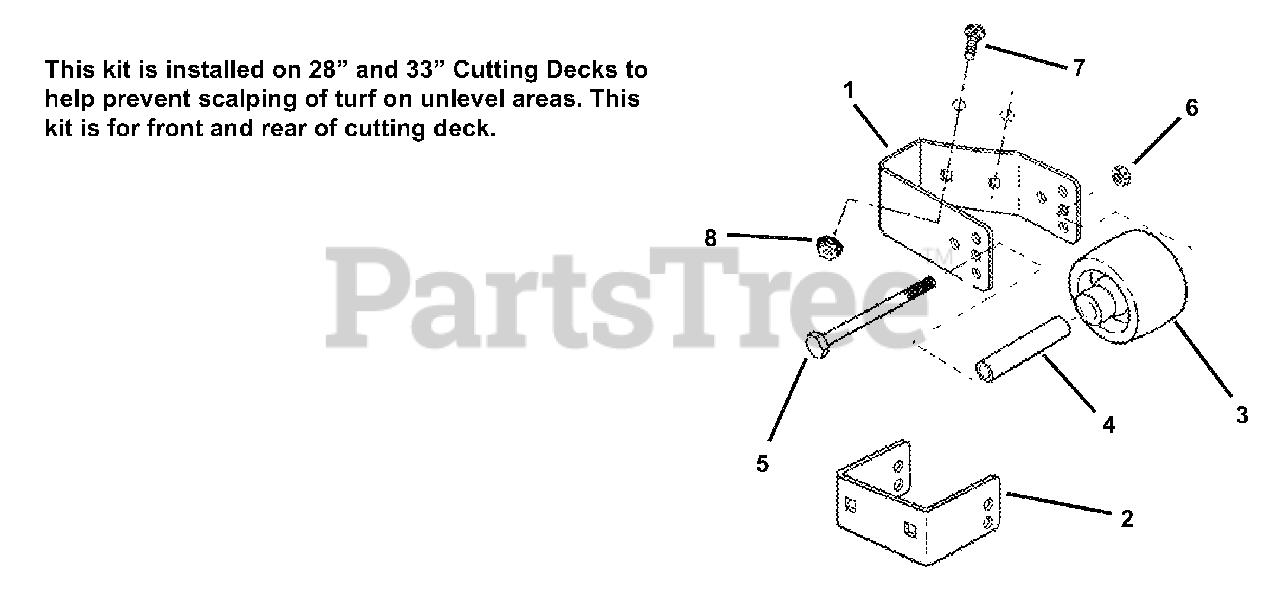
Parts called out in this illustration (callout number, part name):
1	BRACKET, Anti-Scalp (Rear)
2	BRACKET, Anti-Scalp (Front)
3	WHEEL, Gage
4	SPACER, Gage Wheel
5	SCREW, 3/8-24 x 3-3/4" Hex Head Cap
6	NUT, 3/8-24 Hex Center Lock
7	BOLT, 5/16-18 x 1/2" Short Neck Carriage
8	NUT, 5/16-18 Hex Flange Lock
